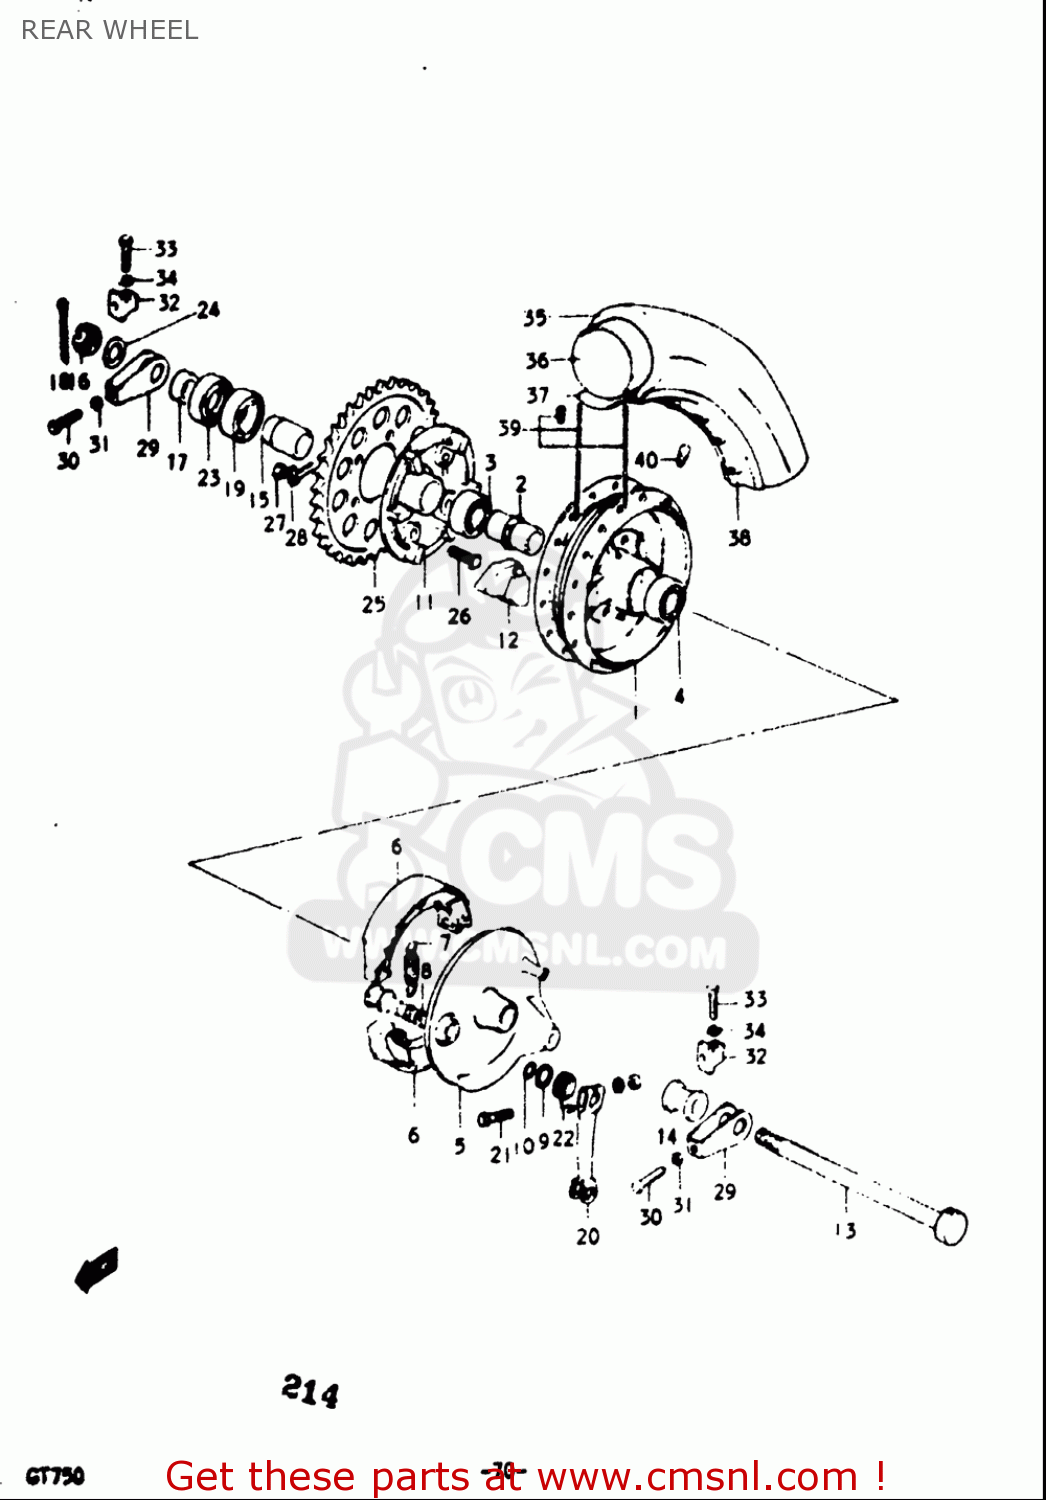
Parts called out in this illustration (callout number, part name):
3	BEARING
4	BEARING(20X47X14)
6	SHOE SET,BRAKE (NAS)
7	SPRING,BRAKE SHOE
8	CAM,RR BRAKE
9	WASHER(15.5X24X1.6)
10	O RING(D:2.4,ID:14.8)
11	DRUM,RR SPROCKET MOUNTING
12	ABSORBER,RR HUB SHOCK
15	SPACER,REAR HUB BEARING
16	NUT 18MM
18	PIN, COTTER
19	BEARING(25X62X17)
21	BOLT
22	SPRING
23	SEAL,OIL(33X62X7)
24	WASHER(19X34X4)
25	SPROCKET,REAR
26	BOLT(10X35.5)
27	NUT
28	WASHER
29	ADJUSTER,CHAIN
30	BOLT(8X50)
31	NUT
32	SUPPORTER,CHAIN ADJUST
33	BOLT
34	WASHER
36	TUBE,INNER
37	PROTECTOR,INNER TUBE
38	RIM,WHEEL
39	SPOKE SET,RR WHEEL
40	BALANCER,WHEEL (B)
